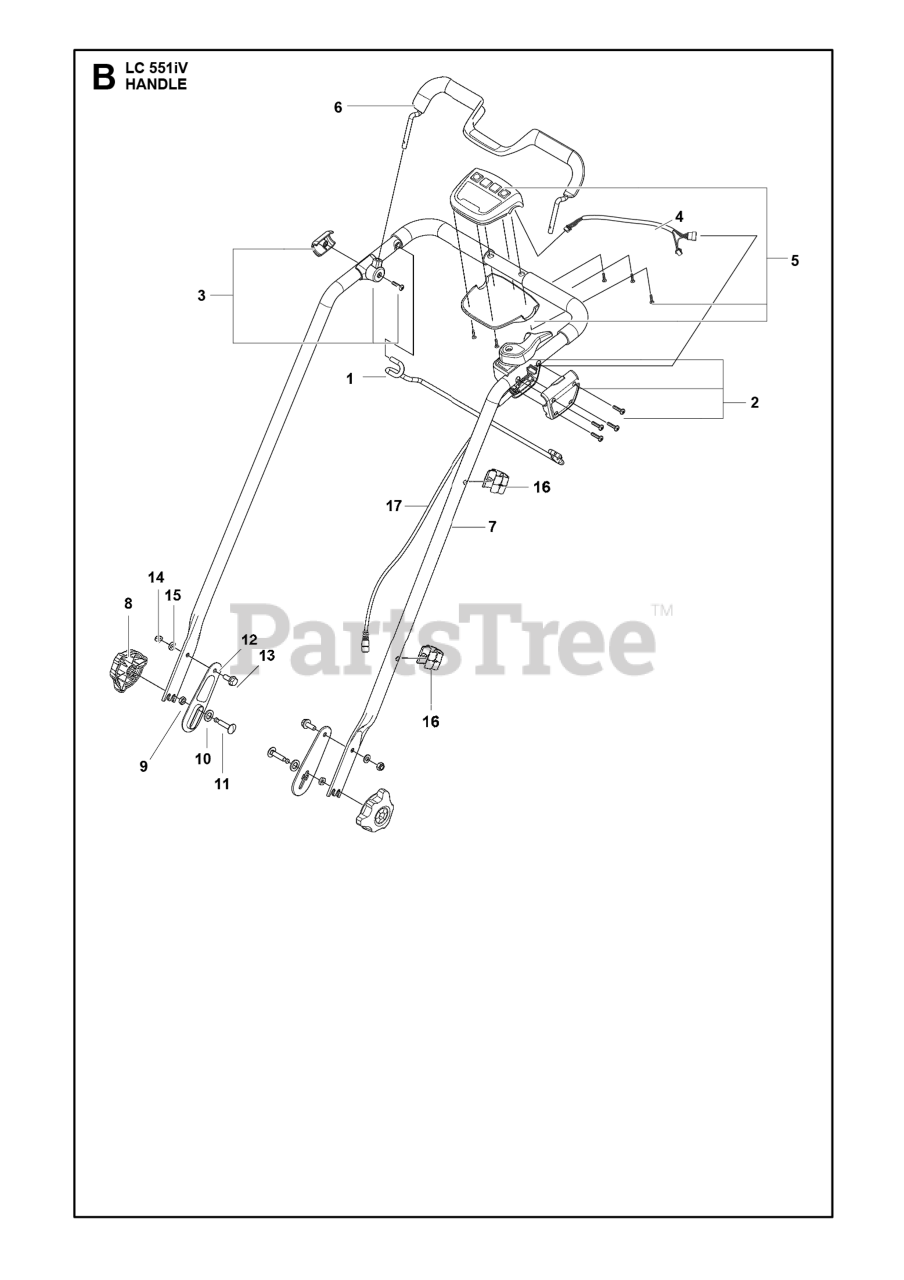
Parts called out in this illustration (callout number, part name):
2	SWITCHBOX ASSY SPARE PART ASSY
3	BAIL ARM ASSY SPARE PART ASSY
4	EXTENSION CABLE CONTROL PANEL
7	Handle Bar
9	NUT ML6M M8
14	LOCKNUT M8
16	CABLE HOLDER HANDLE ASSY
